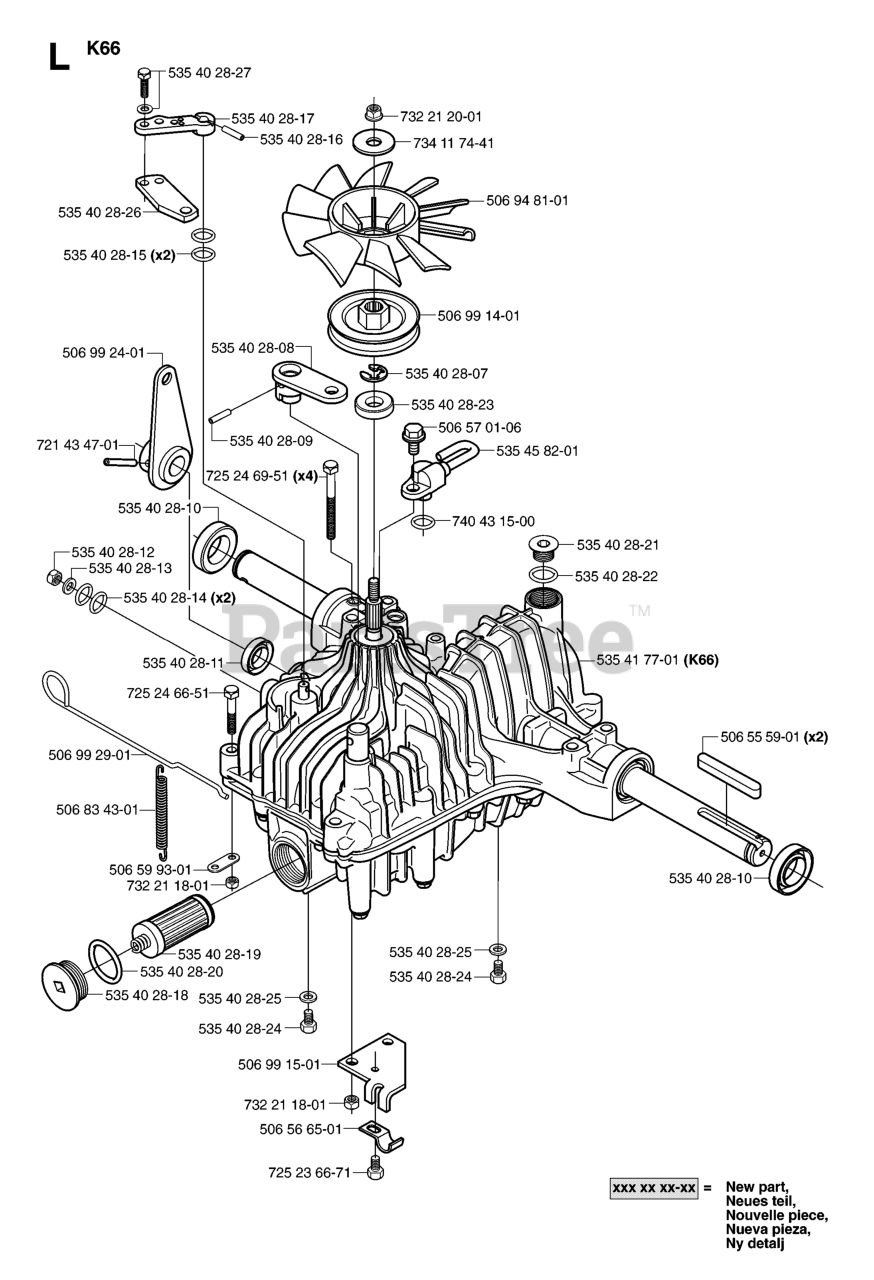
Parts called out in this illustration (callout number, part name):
1	BATTERY 12 VOLT 25 AMP
2	BOLT.HEX.1/4.X.3/4.DICHROMATE
8	BATTERY TRAY T
10	BOLT 1/4-20 X 7.5
11	BATTERY HOLDDOWN FRONT MOUNT
12	NUT, PUSH NYLON 1/4" BATTERY
16	SWITCH INTERLOCK
19	LOCKWASHER
20	NUT
21	HARNESS LIGHT SOCKET
24	BATTERY CABLE GT
25	CABLE BATTERY 6 GA 22" W/16W
27	NUT
28	CABLE GROUND 6 GA 21" 90T BLK
29	PLUNGER SWITCH (COLOR:OLIVE)
30	SWITCH.IGNITION.4.POSITION
31	NUT IGNITION
32	COVER SWITCH KEY
33	KEY.MOLDED.GENERIC
40	WIRING HARNESS
41	BOLT
42	TERMINAL COVER
43	SOLINOID
44	Nut, Keps Blk Hex 1/4-20 UNC
46	HOUR METER T
47	Screw 10-24 x 1/2 Black
50	SWITCH PTO 3 PDT
51	FRAME RETAINING RING
55	Screw 5/16-18 x 1/2 Hex, Self Tapping 5/16-18 x 1/2
80	HARNESS, CLUTCH
81	RELAY.ASSY.T
